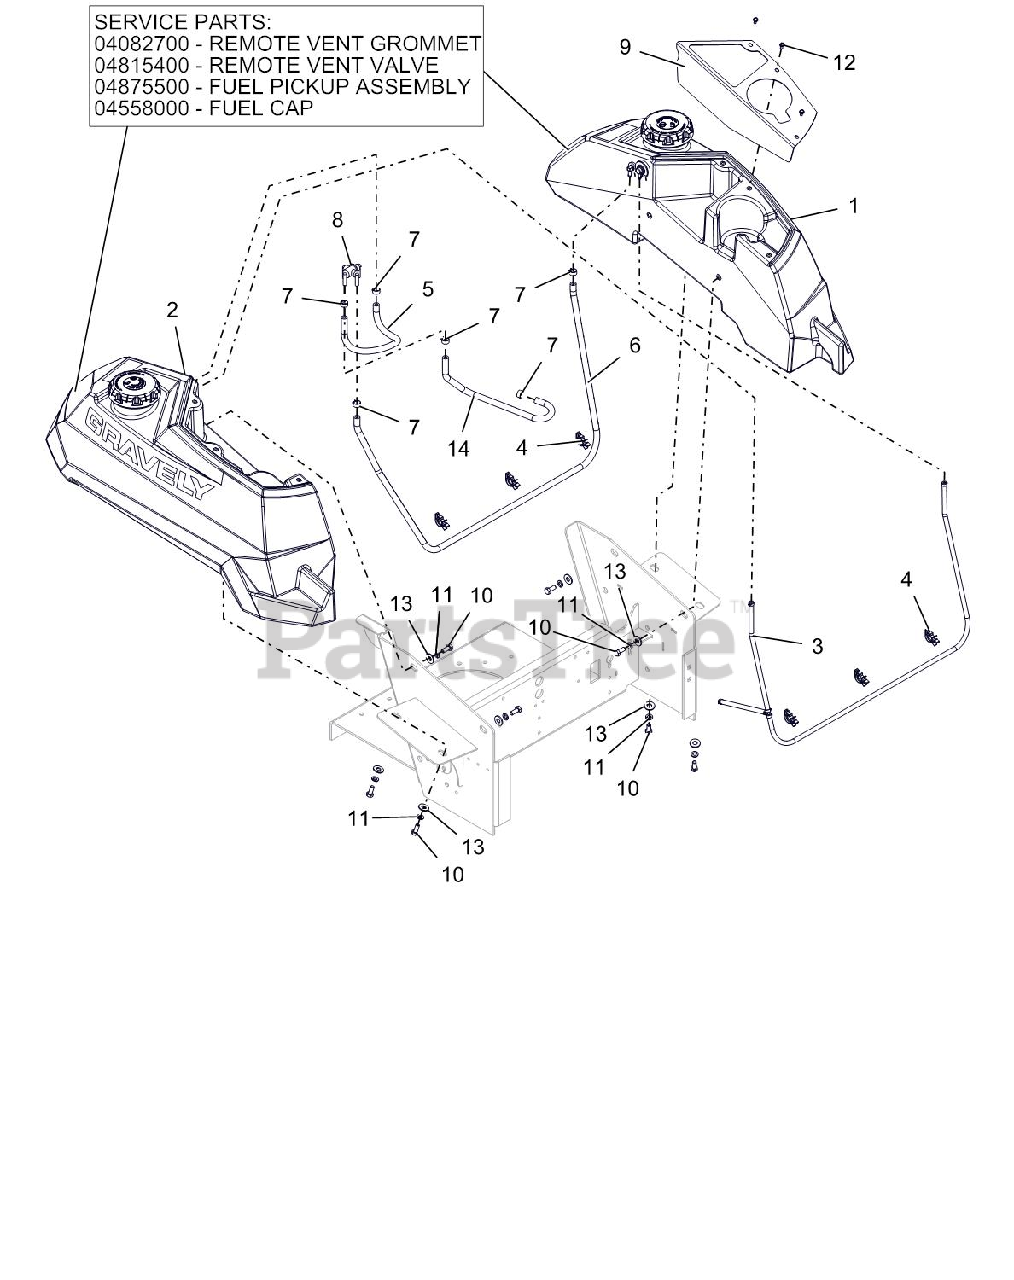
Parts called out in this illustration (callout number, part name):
1	ASM, LH - PT FUEL TANK
2	ASM, RH - PT FUEL TANK
3	ASM, VAPOR LINE
4	WIRE CLIP
5	HOSE, .25 LOW-PERM BULK GAS
6	HOSE, .25 LOW-PERM BULK GAS
7	CLAMP, FUEL LINE
8	VALVE, FUEL
9	PT CUPHOLDER PANEL - RED
10	@BLT-HEX .31-18X.75 GR5 YWZC
11	@WSHR-LK .31X.078 REG YWZC
12	SCR-MCH 10-24X.38 HWHSTAINLESS
13	@WSHR-FL-STL.38X.875X.083 YWZC
14	HOSE, .25 LOW-PERM BULK GAS
15	GROMMET, REMOTE VENT NITRILE
16	VALVE, 2-WAY
17	ASSM,LRG TANK FUEL PICKUP LINE
18	CAP, FUEL VENTIN AUTOLOCK
